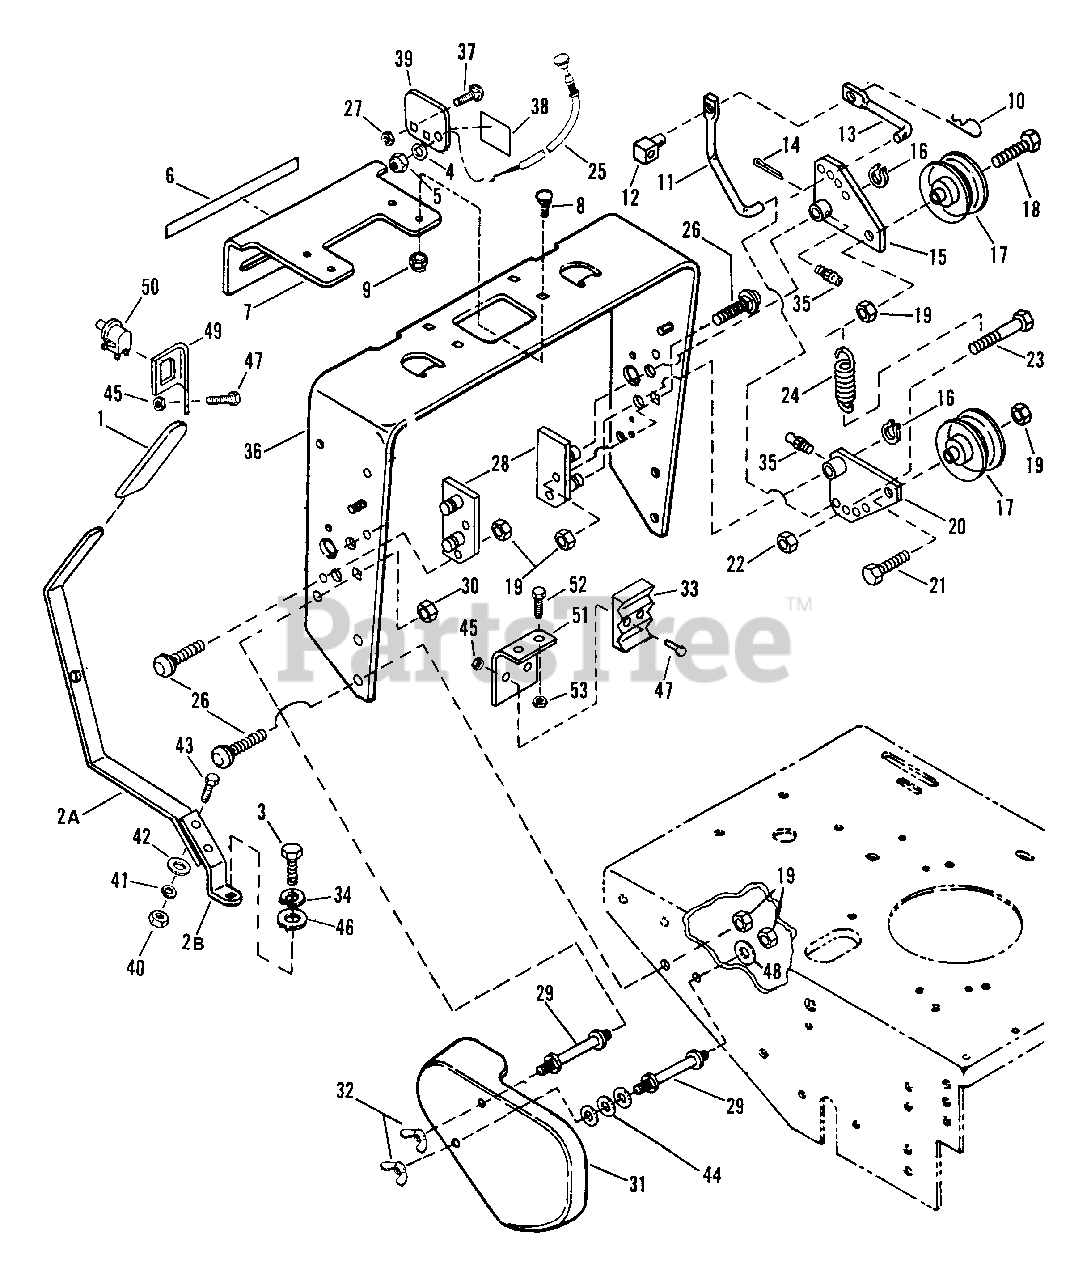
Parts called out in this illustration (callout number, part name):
1	GRIP, Shift Lever
2A	LEVER, Upper Shifter
2B	LEVER, Lower Shifter
3	HHCS, 1/4-20 X 0.625, GR5, ZINC/CLEAR
4	WASHER, 3/8 Internal Tooth Lock (Briggs)
5	NUT, 3/8-24 HEX
6	DECAL, Shift
7	QUADRANT, Shift
8	SCREW, 1/4-20 x 3/4" Short Neck Carriage
9	NUT, 1/4-20 Hex, Nyloc
10	HAIR-PIN, 3/32 x 1 3/16"
11	LINK, Long (Left Hand)
12	SWIVEL
13	LINK, Short
14	COTTER-PIN, 3/32 x 1"
15	WELDMENT, Idler
16	RING, 5/8" External Retaining
17	PULLEY, Idler
18	SCREW, 3/8-16 x 2-1/2" Hex Head Cap
19	NUT, 3/8-16 HEX NYLON LOCK
20	WELDMENT, Idler (Lower Left & Upper Right Sides)
21	BOLT, 3/8-16 X 2, GD5, CZ
22	NUT, 5/16-18 Hex Flange Lock
23	BOLT, 5/16-18 X 3/4 GD5
24	SPRING, Extension
25	CABLE, Choke (Briggs)
26	BOLT, 3/8-16 x 1" Carriage
27	NUT, 1/4-20 HEX NYLON LOCK
28	WELDMENT, Idler Pivot (Left Hand)
29	STUD, Fender Mount
30	NUT, 3/8-16 Hex Jam
31	FENDER, Left Hand
32	WING-NUT, 3/8-16
33	MODULE
34	WASHER, 1/4 Internal Tooth Lock
35	FITTING, Lube
36	BRACKET, Tank
37	BOLT, 1/4-20 x Carriage
38	DECAL, Caution
39	PLATE, Caution Decal
40	NUT, 5/16-18 HEX
41	WASHER, Lock
42	WASHER, Flat
43	BOLT, 5/16-18 X 1-1/4 GD5 YZ
44	WASHER, 3/8" USS
45	NUT, 1/4-20 HEX NYLON LOCK
46	WASHER, 1/4 Flat
47	BOLT, 1/4-20 x 3/4"
48	WASHER, 1/2 Flat
49	BRACKET, Reverse Switch
50	SWITCH, Seat
51	BRACKET
52	BOLT, 5/16-18 x 3/4"
53	NUT, 5/16-18 HEX NYLON LOCK
